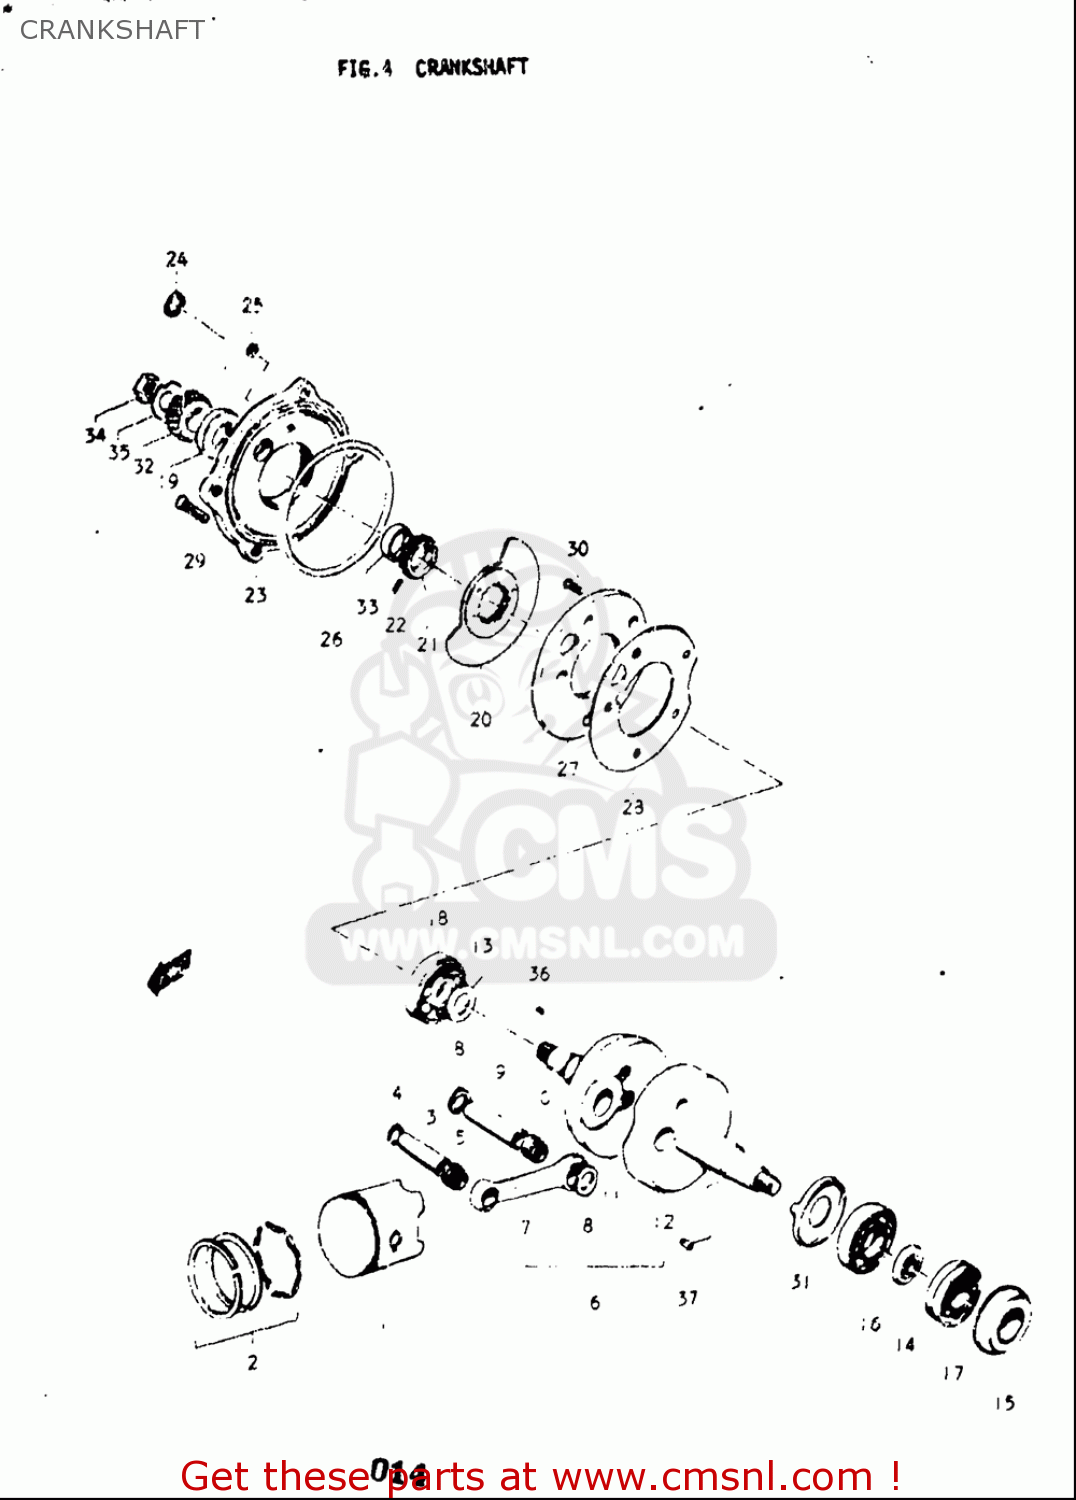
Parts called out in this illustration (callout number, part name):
1	PISTON
2	RING SET,PISTON
3	PIN,PISTON 14MM
4	RING,SNAP 14MM
5	BEARING(14X18X19.8)
6	CRANKSHAFT ASSY
7	ROD,CONNECTING
8	WASHER(19X32X1)
9	PIN,CRANK
10	BEARING(19X25X16)
11	CRANKSHAFT,R
12	CRANKSHAFT,L
13	SHIM(20X28X0.5)
15	SEAL,OIL(19.6X37X8)
16	BEARING(20X52X15)
17	BEARING(20X47X14)
18	BEARING(20X52X15)
19	OIL SEAL (25X44X7)
21	GUIDE,ROTERY VALVE
22	PIN
23	SEAT,CRANK OUTER VALVE
24	O RING(D:1.9,ID:22.6)
25	O RING(D:1.5,ID:10)
26	O RING(D:2,ID:99)
29	SCREW
30	SCREW
34	NUT
35	WASHER
36	KEY
37	KEY
